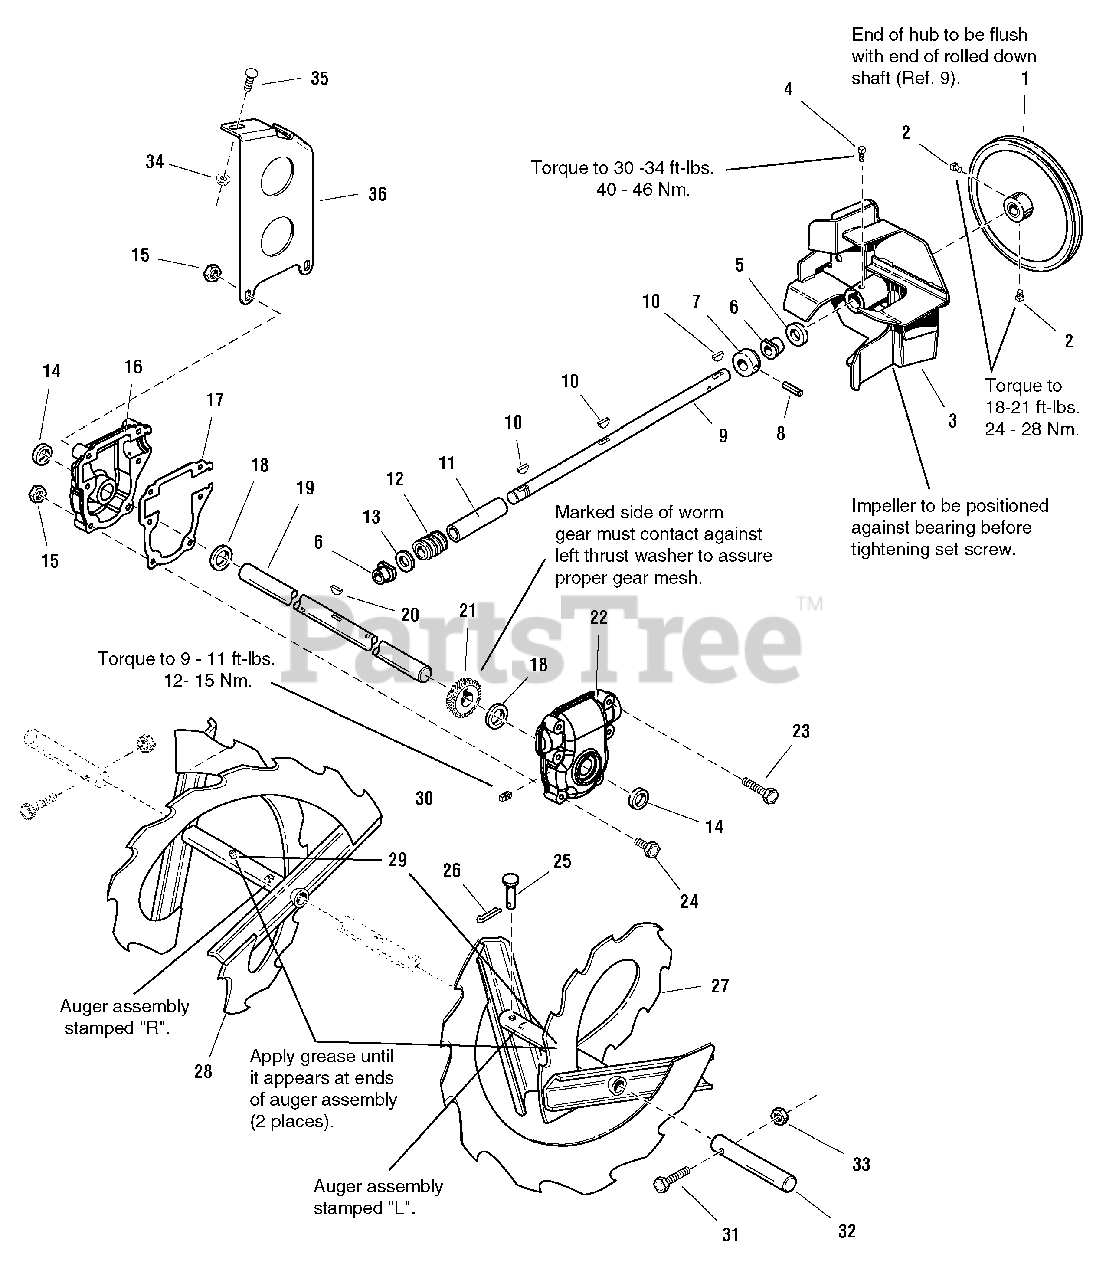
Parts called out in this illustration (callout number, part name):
1	PULLEY, w/Hub
2	SCREW, Set Square Head Cup Point, 5/16-18 x 1/2 G8
3	IMPELLER ASSEMBLY
4	SCREW, Set Square Head Cup Point, 3/8-16 x 1/2 G8
5	SEAL, Oil 1/4" Thick
6	BUSHING, 377/500 ID x 1-1/10 OD x 1-1/100 LG Powerdered Metal
7	COLLAR, Thrust 3/4 LG
8	PIN, Drive Lock Type A 3/16 x 1-1/2
9	SHAFT, Worm 18-1/10 LG
10	KEY, Woodruff, 47/250 x 5/8
11	TUBE, 9/10 OD 39/50 ID, 7-1/2 LG
12	GEAR, Worm 1-3/8 LG
13	WASHER, Thrust
14	SEAL, Oil, 1/4" Thick
15	NUT, Hex Flange, 1/4-20 Toplock Small
16	CASE, Gear R.H.
17	GASKET, Gear Case
18	WASHER, Thrust
19	SHAFT, 16 LG Auger 3 Holes
20	KEY, Woodruff 1/4 x 3/4
21	GEAR, Worm 7/8 LG
22	CASE, Gear L.H.
23	CAPSCREW, Hex Head, 1/4-20 x 2-1/2 G5
24	CAPSCREW, Hex Head, 1/4-20 x 2-1/4 G5
25	PIN, Flat Head Drilled
26	PIN, Cotter 47/50 x 3/4
27	AUGER ASSEMBLY, L.H. 9-1/2 LG
27	AUGER ASSEMBLY, L.H. 11-1/2 LG
27	AUGER ASSEMBLY, L.H. 13-1/2 LG
27	AUGER ASSEMBLY, L.H. 15-9/10 LG
28	AUGER ASSEMBLY, R.H. 9-1/2 LG
28	AUGER ASSEMBLY, R.H. 11-1/2 LG
28	AUGER ASSEMBLY, R.H. 13-1/2 LG
28	AUGER ASSEMBLY, R.H. 15-9/10 LG
29	FITTING, Lube 1/4 Drive, No Check Ball
30	FITTING, Pipe Plug, Square Head
31	CAPSCREW, Hex Head, 1/4-20 x 1-3/4 G5
32	SHAFT, E-Coat, 5 LG
33	NUT, Hex Lock ESNA Light, 1/4-20NC-3B
34	NUT, Hex Flange, 5/16-18, Whiz Lock Small
35	CARRIAGE BOLT, 5/16-18 x 3/4 G5
36	SUPPORT, Gear Box 10GA
